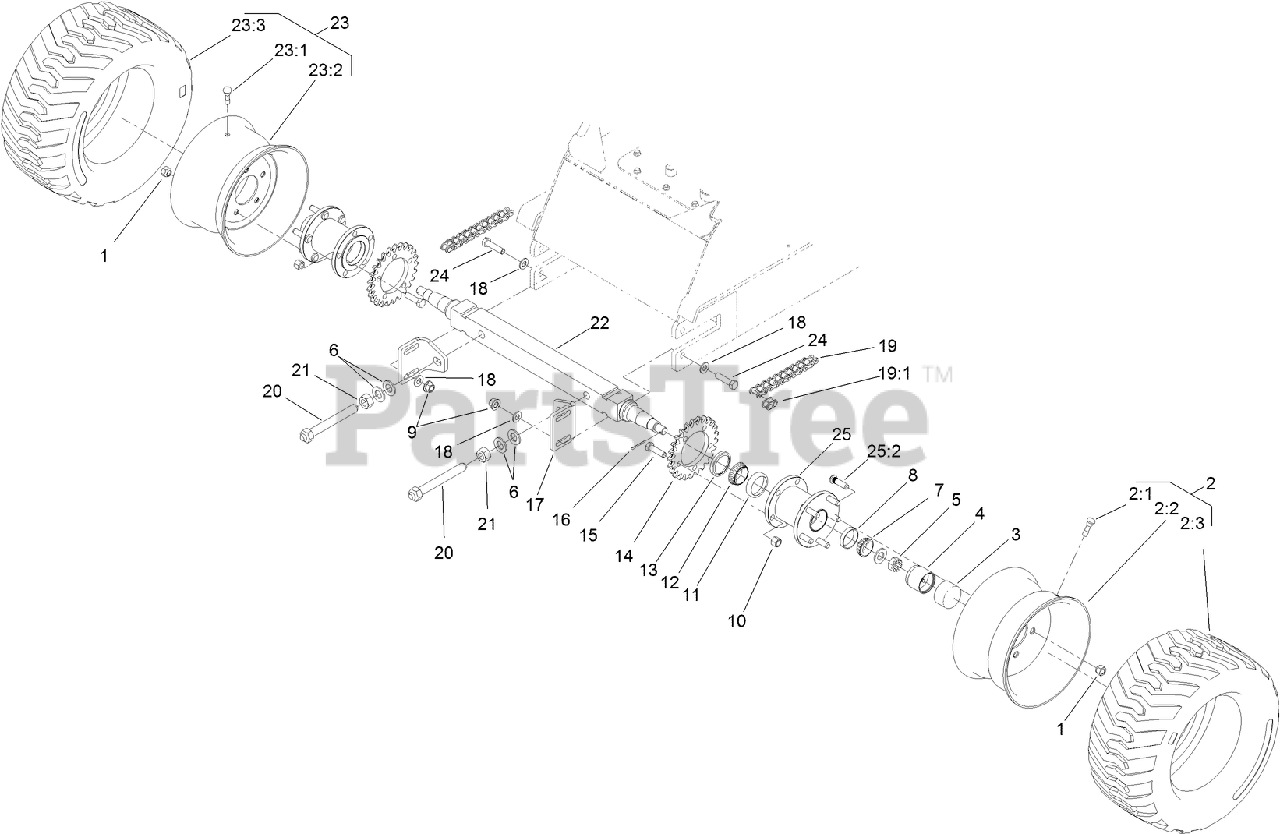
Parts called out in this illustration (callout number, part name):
1	NUT-LUG
2	LH WHEEL AND TIRE ASM
2:1	STEM-VALVE
2:2	WHEEL
3	CAP-PROTECTOR, BEARING
4	PROTECTOR-BEARING
5	NUT-HEX, SLOTTED
6	WASHER-FLAT
7	BEARING-CONE, TAPERED
8	BEARING-CUP, TAPERED
9	NUT-LOCK
10	NUT-LOCK, NI
11	CUP-BEARING, TAPERED
12	CONE-BEARING, TAPERED
13	SEAL-BEARING, WHEEL
14	SPROCKET-25T
15	SCREW-HH
16	PIN-COTTER
17	BRACKET-AXLE
18	WASHER-FLAT
19	CHAIN-ROLLER
19:1	LINK-CONNECTING
20	BOLT-TENSION
21	NUT-HEX
23	RH WHEEL AND TIRE ASM
23:1	STEM-VALVE
23:2	WHEEL
24	SCREW-HH
25	FRONT HUB ASM
25:2	STUD-TYPE, DRIVE
